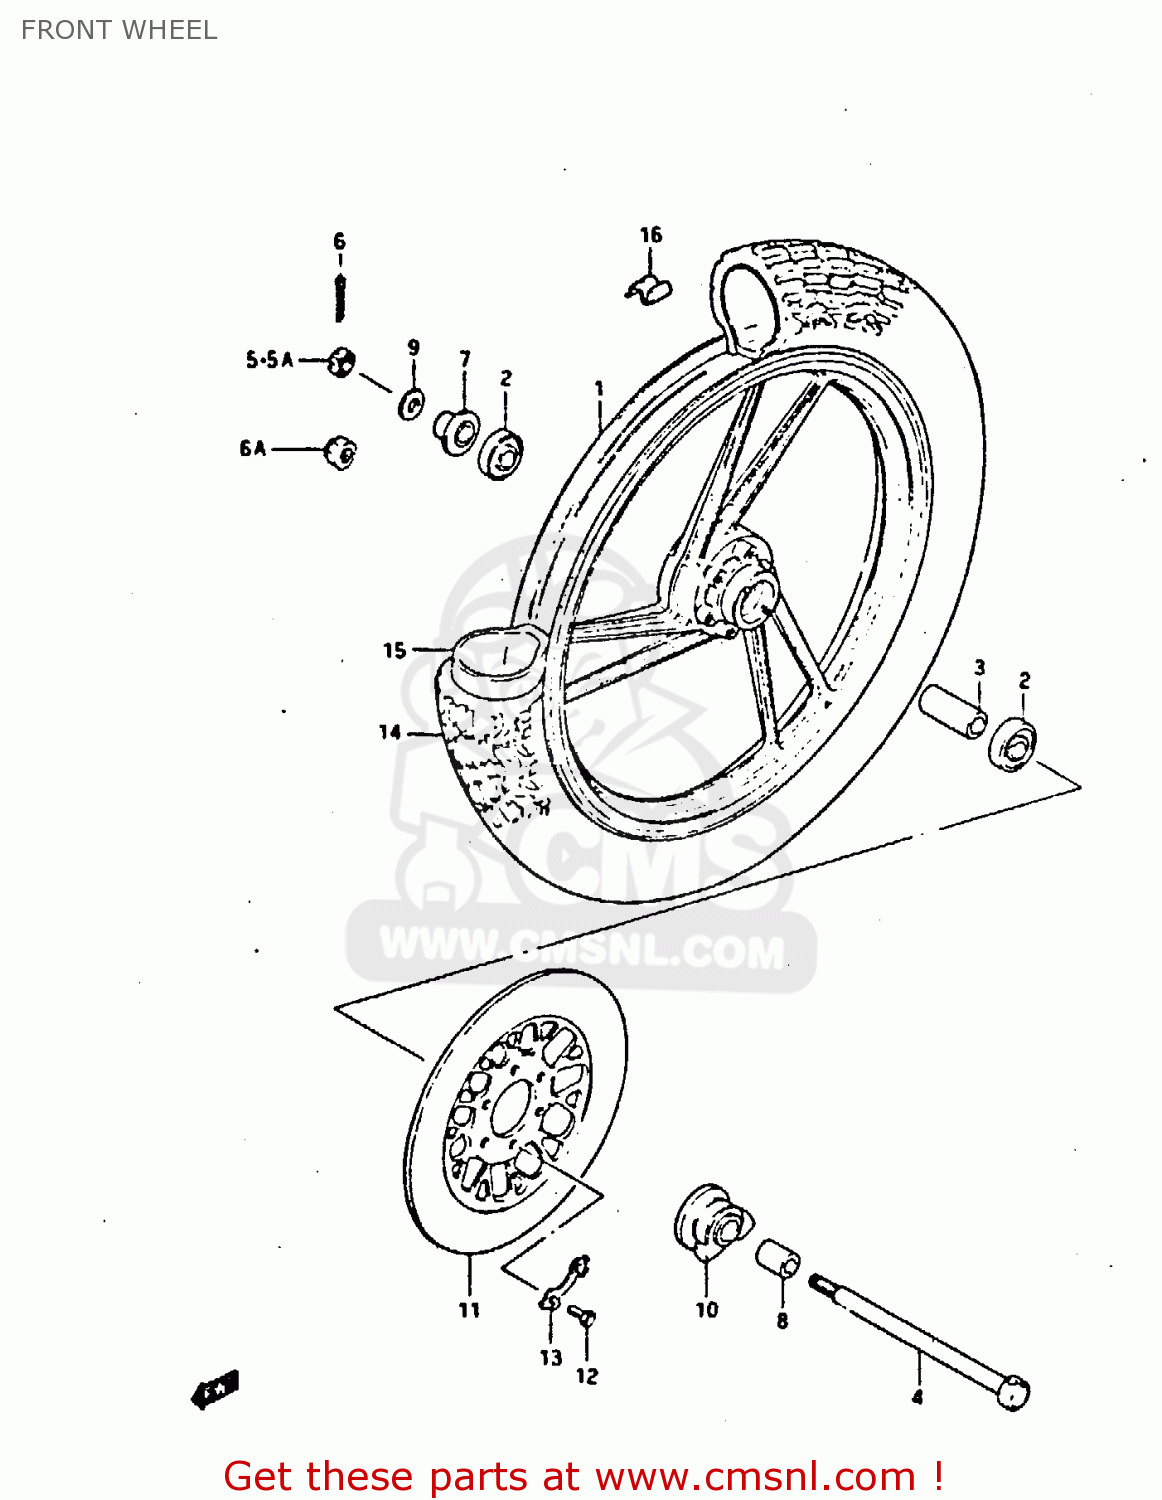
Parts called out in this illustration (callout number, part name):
1	WHEEL, FRONT (18X1.60) GOLD
2	BEARING
3	SPACER(15.3X21.7X63)
4	AXLE,FRONT
5	NUT 12MM
5A	NUT
6	COTTER PIN
6A	NUT
7	SPACER,FR HUB BEARING,R
8	SPACER(15X22X30)
9	WASHER
10	BOX ASSEMBLY,SPEEDOMETER GEAR
11	DISC,FR BRAKE
12	BOLT(8X25)
13	WASHER
14	TIRE,FRONT
15	TUBE,INNER
16	BALANCER,WHEEL
